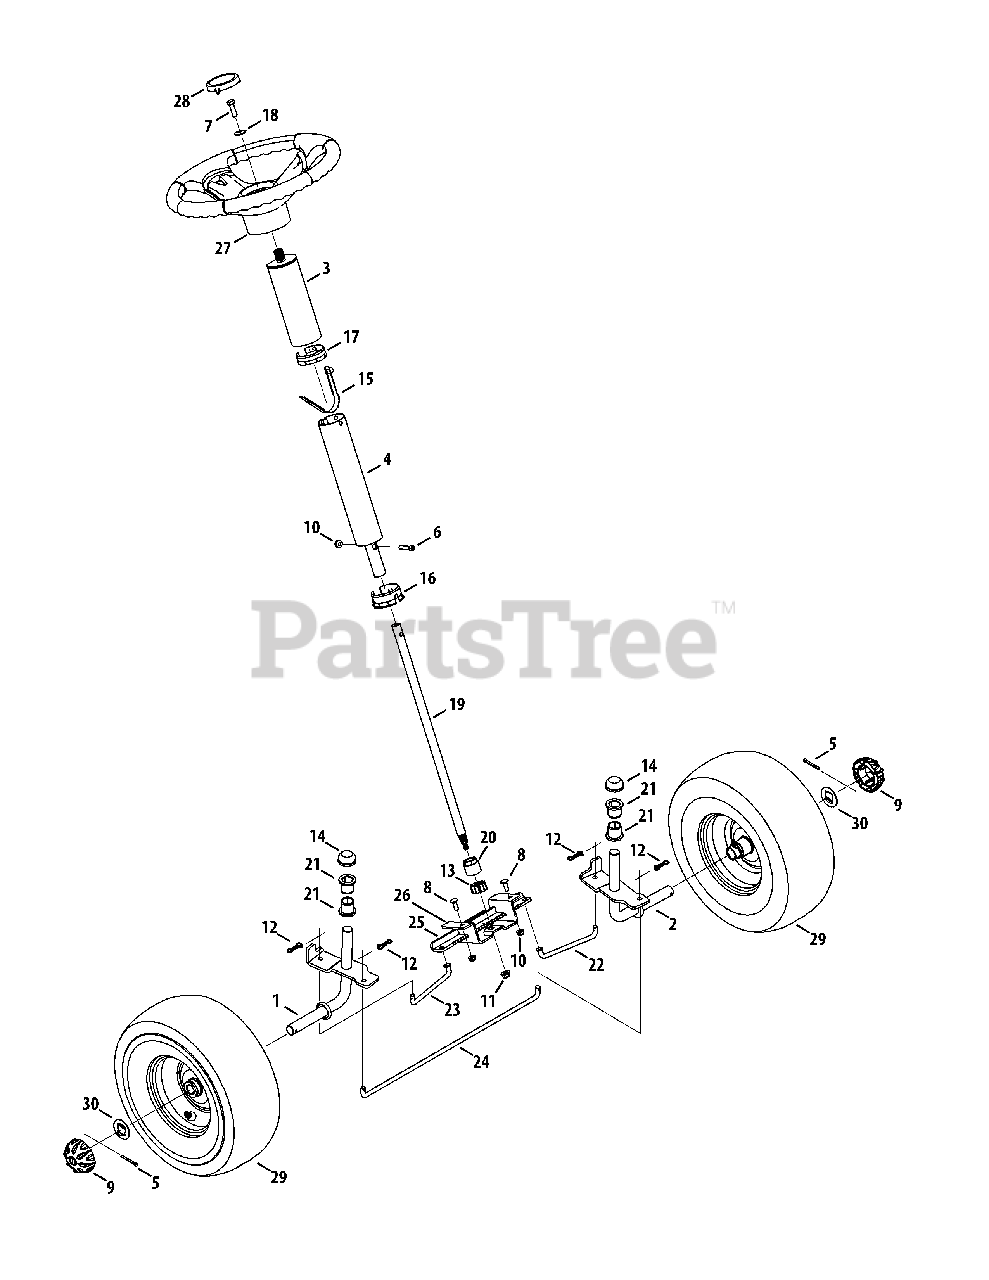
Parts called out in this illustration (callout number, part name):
1	Front Axle Assembly, RH
2	Front Axle Assembly, LH
3	Upper Tube Assembly
4	Lower Tube Assembly
5	Cotter Pin, 5/32 x 1.25
6	Shoulder Screw, .375 x .148 x 1/4-20
7	Hex Head Screw, 5/16-18:1.00
8	Carriage Screw, 1/4-20, .75
9	Hub Cap
10	Flange Lock Nut, 1/4-20
11	Flange Lock Nut, 5/16-18
12	Bow-Tie Cotter Pin, 72
13	Steering Pinion Gear
14	Push Cap, 3/4
16	Lower Steering Collar
17	Upper Steering Collar
18	Bevel Washer, .340X.872X.060
19	Steering Shaft, .625 OD X 18.03
20	Hex Flange Bearing, 5/8
21	Flange Bearing, .760 X .941 X 1.0
22	Steering Rod, LH
23	Steering Rod, RH
24	Front Tie Rod
25	Steering Rack Plate
26	Lower Steering Bearing
27	Steering Wheel, Soft Grip
28	No Sprig Cap
29	Complete Wheel Assembly
30	Washer, .781 x 1.59
